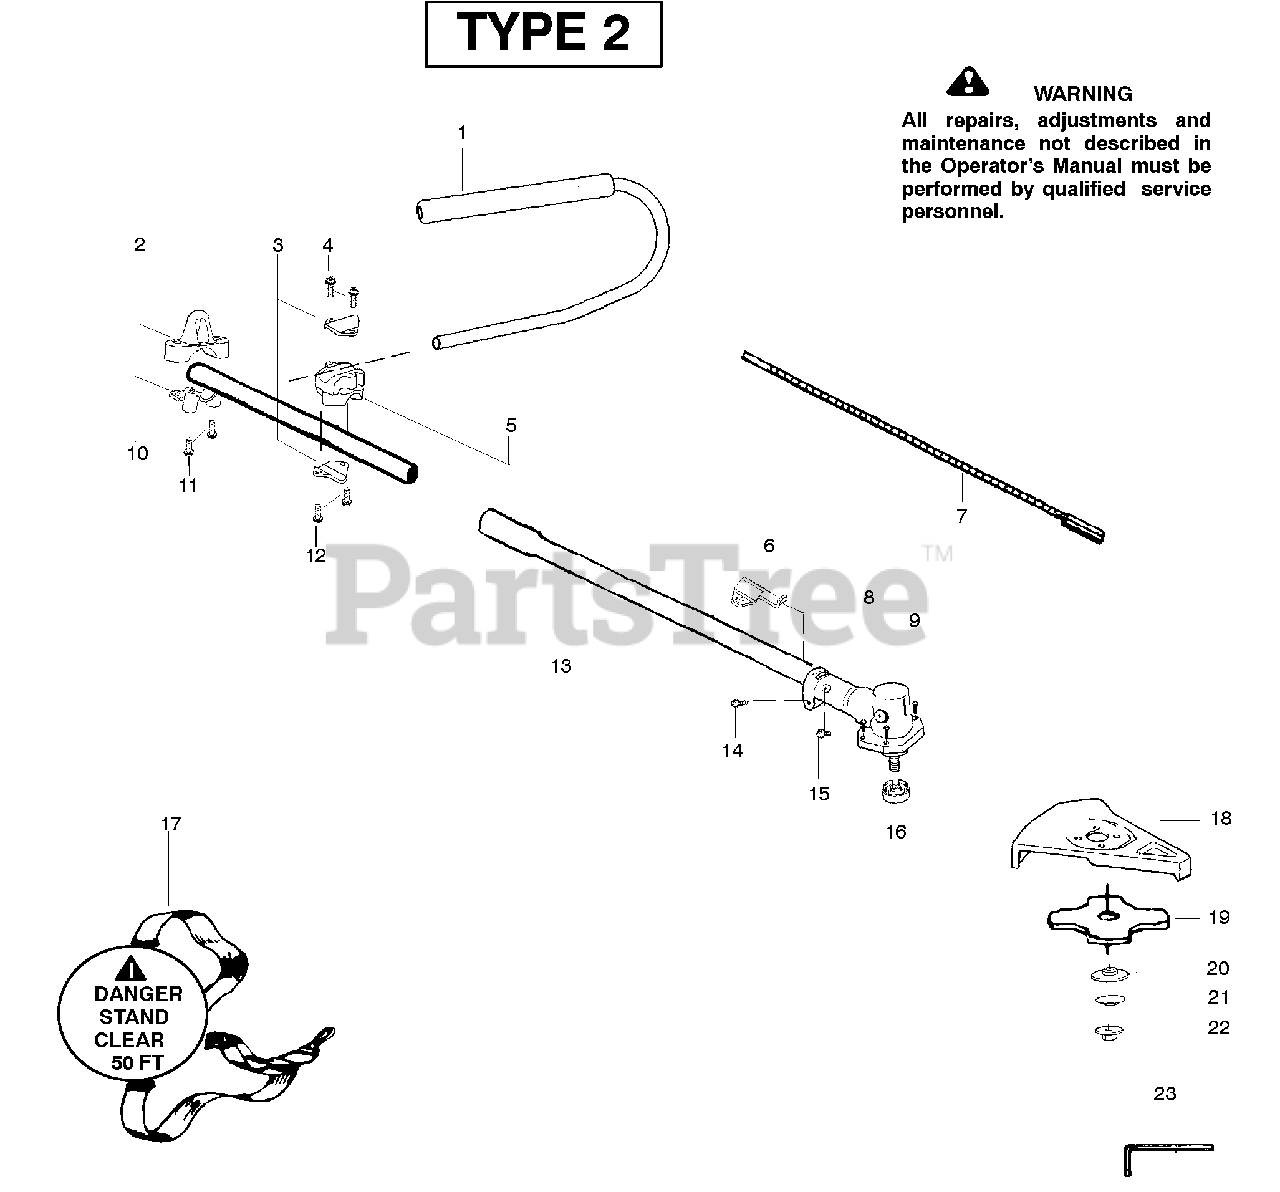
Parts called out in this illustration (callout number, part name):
1	Kit-Handlebar
2	Clamp-Harness Upper
3	Clamp-Bracket
5	Clamp-Handlebar (7/8")
5	Clamp-Handlebar (1")
6	Bracket-Shield
7	Flexshaft-Split boom
10	Clamp-Harness Lower
13	Assy.-Driveshaft
15	Screw-Alignment
16	Dust cup - Blade
17	Assy-Shoulder Strap
18	Kit-Blade Shield
19	Accy.-Weed Blade (8")
20	Washer-Blade Retaining
21	Washer-Belleville
23	Wrench-Hex (5/32")
